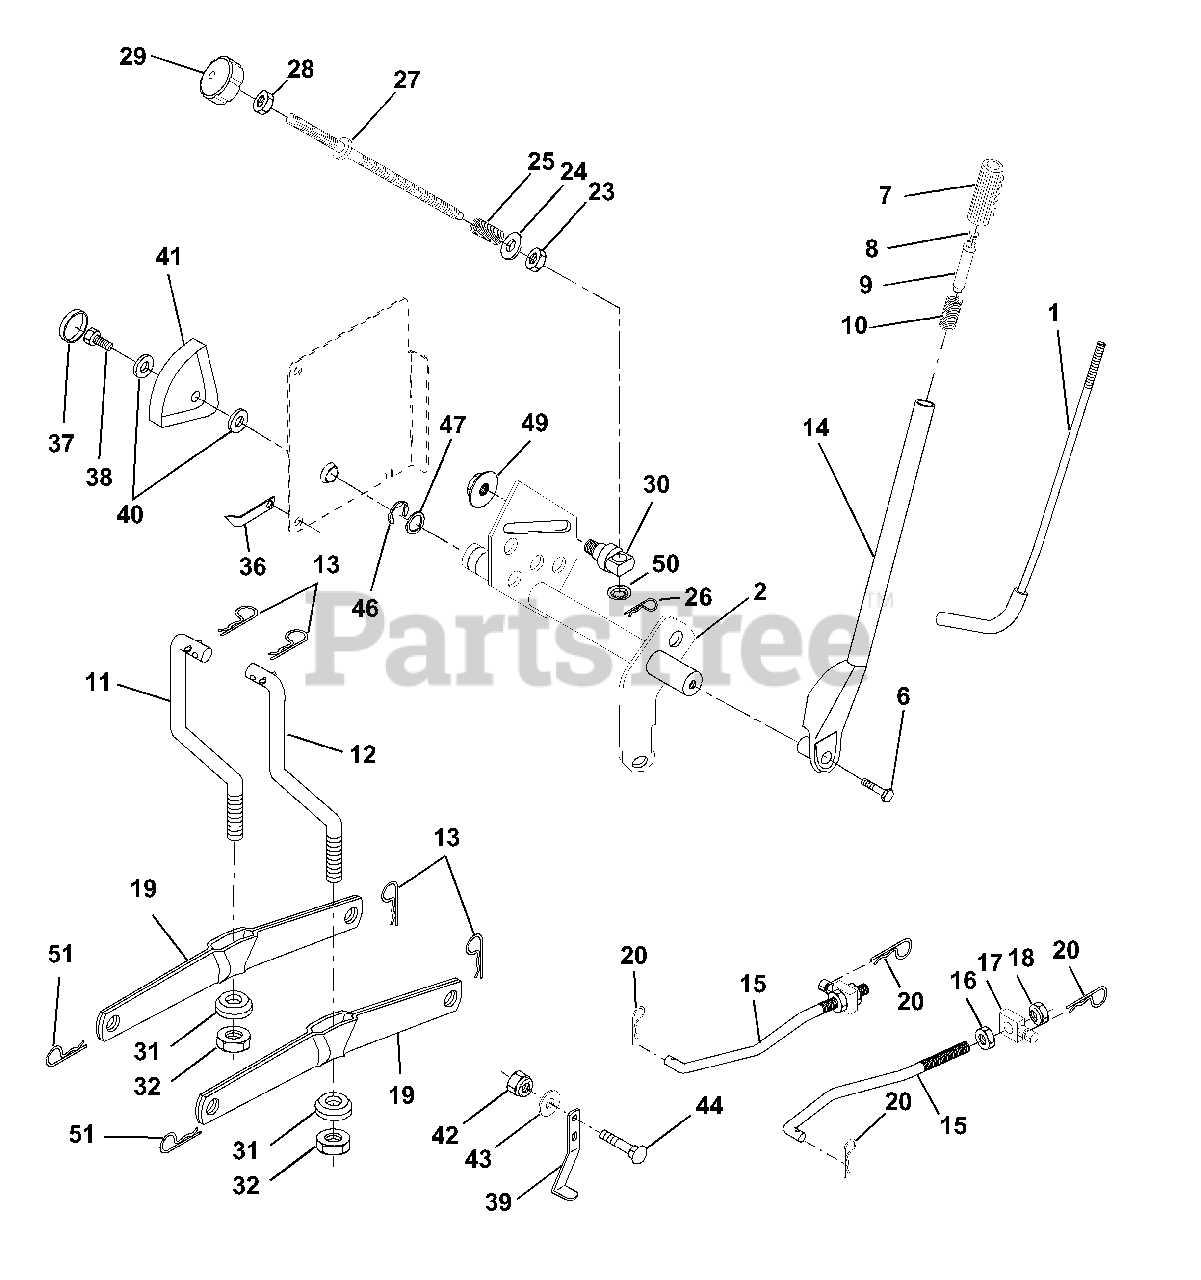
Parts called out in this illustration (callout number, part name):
1	Wire Asm Inner W/Plunger
2	Shaft Asm Lift
3	Pin Groove
4	E Ring #5133-62
5	Washer 29/32 x 1-1/4 x 21 Ga.
6	Bearing Nylon Blk .629 ID
7	Grip Handle Fluted
8	Button, Plunger
11	Link Lift Lh CRD
12	Link Lift Rh CRD
13	Retainer Spring
15	Link Front
16	Nut Jam Hex 1/2-13 Unc
17	Trunnion Blk Zinc
18	Nut Crownlock 1/2-13 Unc
19	Arm Suspension Rear
20	Spring Retainer
23	Nut Special
24	Washer 13/32 X 5/8 X 16 Ga
25	Spring
26	Retainer Clip
27	Rod Adjust Lift
28	Nut Hex Jam 3/8-16 Unc
29	Knob Infinite 3/8-16 Unc Black
30	Trunnion Infinite Height
31	Bearing Pvt. Lift Spherical
32	Nut Lock 3/8-24
36	Pointer Height Indicator
38	Screw 5/16-18 x 1
40	Washer 11/32 x 1-1/2
41	Scale Ind Height Blk
49	Nut Hex Flange Lock
50	Nut Push Phos & Oil
51	Retainer Spring
